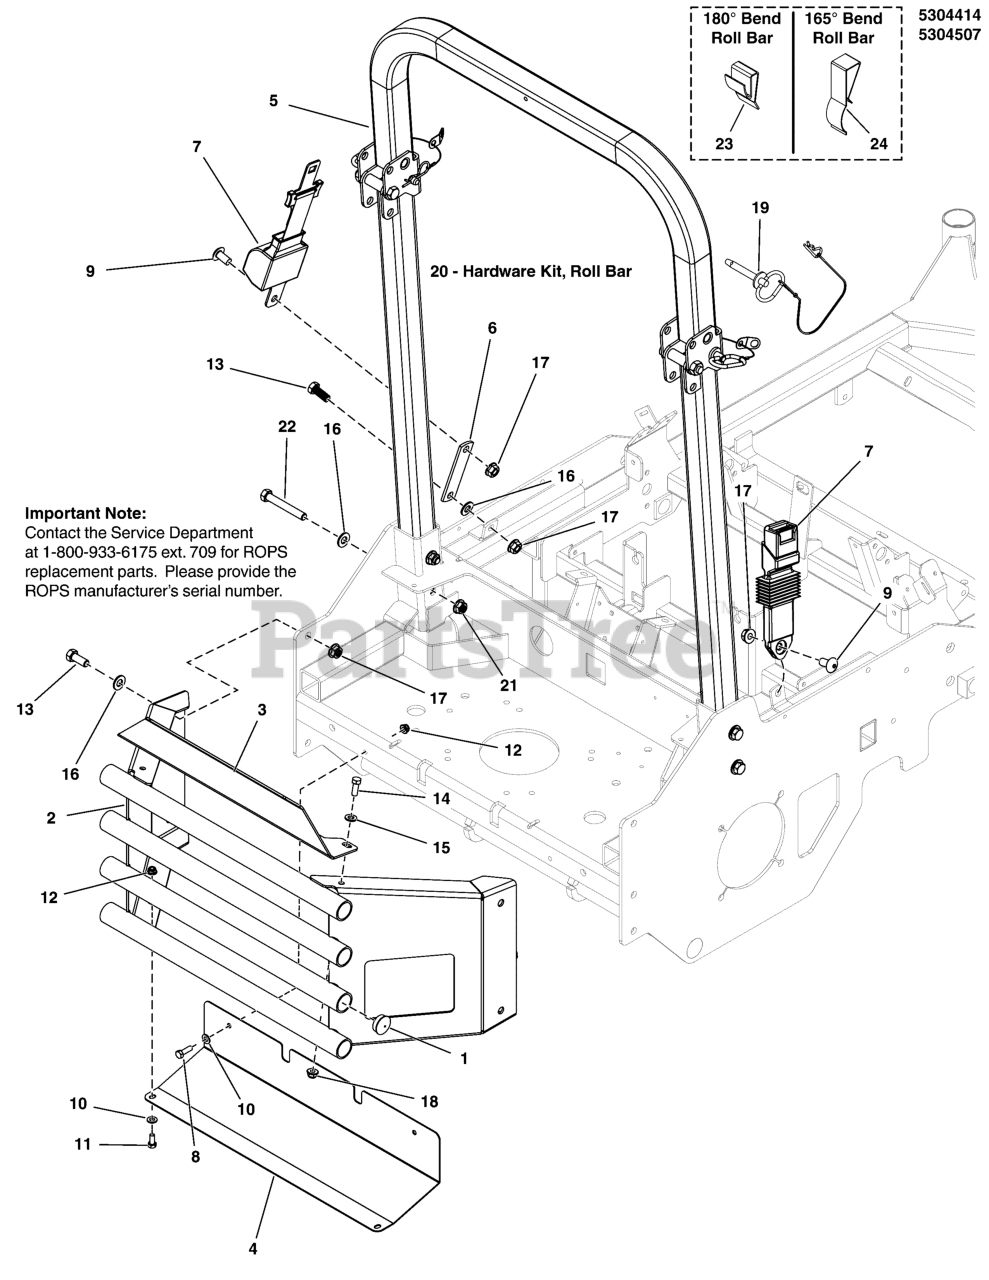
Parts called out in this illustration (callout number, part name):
1	PLUG, PANEL, 1.25 - BLACK
2	WELD, BUMPER, F320Z - RED
3	PLATE, CARB PROTECTOR, F320Z - RED
4	PLATE, HEAT SHIELD - BLK
5	ROPS, S200XT & F320
6	EXTENSION, SEAT BELT - BLK
7	SEAT BELT ASSM, RETRACTOR + SUP SLEEVE
8	BOLT, 5/16-18 X 1 GD5 CZ
9	SCREW, 1/2-13 X 1.00, SHCS
10	WASHER, 5/16" SAE
11	BOLT, 5/16-18 X 3/4 GD5
12	NUT, 5/16-18 HEX NYLOCK FLANGE
13	BOLT, 1/2-13 X 1-1/4 GD5 CZ
14	BOLT, 3/8-16 X 1" GD5 CZ
15	WASHER, 3/8 GD.9 FLAT
16	WASHER, 1/2 SAE
17	NUT, Hex Flange, Nylock, 1/2-13
18	NUT, 3/8-16 HEX NYLOCK FLANGE
19	PIN, HITCH, .50 X 3.25 W/ LAY
20	HARDWARE KIT, ROLL BAR
21	NUT, 1/2-13 HEX SIDE LOCK
22	BOLT, 1/2-13 X 3-1/4, HEX HD, GD5, CZ (SV)
23	ANTI-RATTLE SPRING, FEMCO #230328972 (SV)
24	ANTI-RATTLE SPRING, ROPS, 165 DEGREE (SV)
